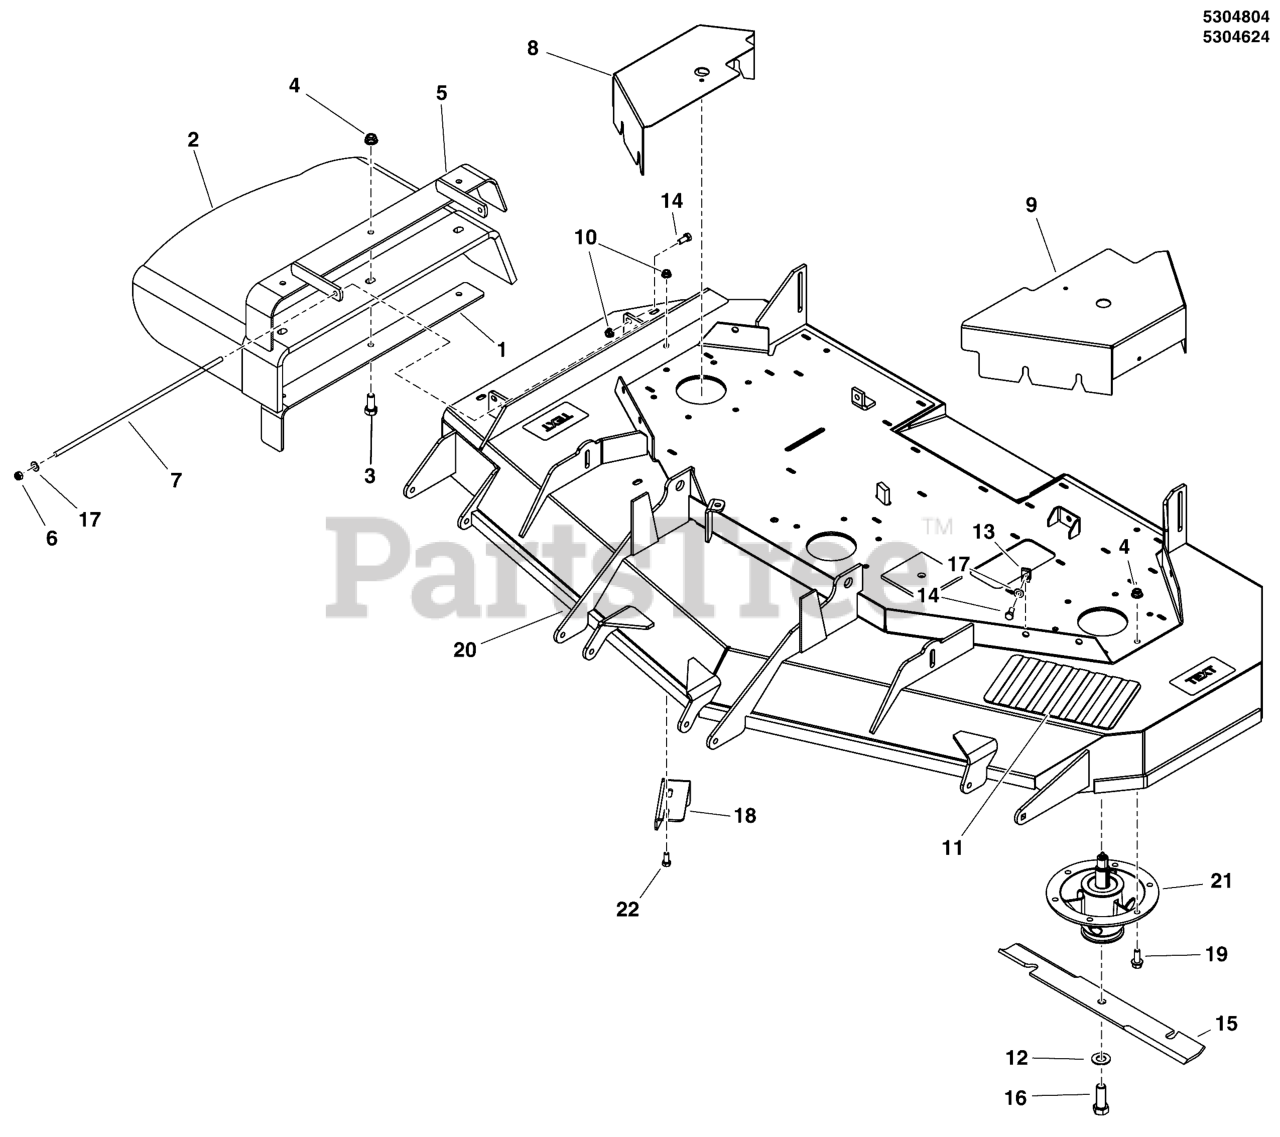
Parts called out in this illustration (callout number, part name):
1	SUPPORT, DISCHARGE CHUTE - BLK
2	CHUTE, RUBBER DISCHARGE (5104442)
3	BOLT, 3/8-16 X 1-1/2, CARRIAGE, GD5, CZ
4	NUT, 3/8 - 16 HEX NYLOCK FLANGE
6	NUT, 5/16-24 HEX NYLON LOCK
7	ROD, MOUNT, CHUTE, 61, CZ
8	GUARD, MOWER DECK, IS2100-61, RH - RED
9	GUARD, MOWER DECK, IS2100-61, LH - RED
10	NUT, 5/16-18 HEX NYLOCK FLANGE NUT
11	SAFETY WALK, 9.75 X 6.00
12	WASHER, BLADE BOLT, 9/16" F436, CZ
13	BODY CLIP, 5/16-18-7GA MATERIAL
14	BOLT, 5/16-18 X 3/4 GD5
15	BLADE SET, 61 DECK (3)
16	BOLT, 5/8-11 X 1-3/4 GD8
17	WASHER, 5/16" SAE
18	PLATE, DEFLECTOR - BLK
19	BOLT, 3/8-16 X 1, FLANGE, GD 5, CZ
20	DECK SHELL W/DECALS, 61, F210Z (5415427B)
20	DECK SHELL W/DECALS, F210Z-61 (5422050B)
21	SPINDLE ASSM, CAST IRON 8.0-6 BOLT, LS
22	BOLT, 5/16-18 X 3/4, CARRIAGE, GD5, CZ
